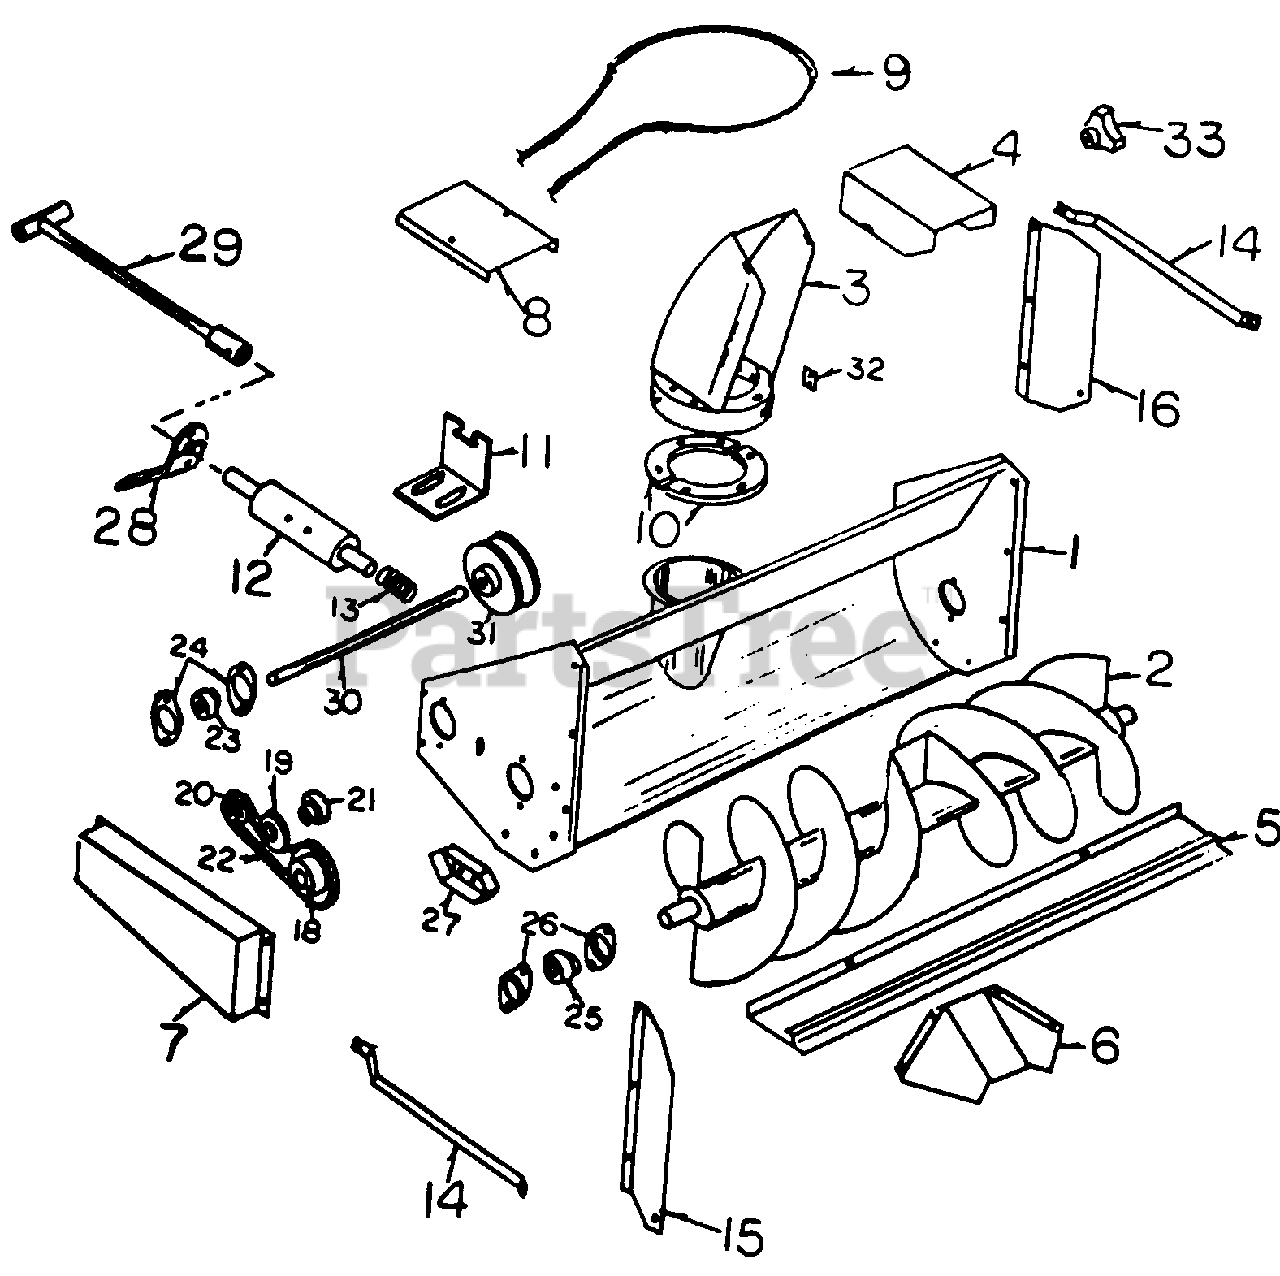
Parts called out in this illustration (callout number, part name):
1	Snow Blower Housing
2	Auger
3	Chute
4	Snow Deflector
5	Snow Blower Bit
6	Snow Retainer
7	Chain Cuard
8	Belt Cuard
9	Cable, 1/8" x 84"
10	Chute Clamp
11	Cable Retainer
12	Cable Pulley
13	Spring
14	Extender Brace
15	Extender, RH
16	Extender, LH
18	Auger Sprocket
19	Idler Sprocket
20	Drive Sprocket(1800)
20	Drive Sprocket(2000)
21	Idler Sprocket Bushing
22	Chain
23	Bearing, 3/4"
24	Bearing Flange, 3/4"
25	Bearing, 1"
26	Bearing Flange, 1"
27	Skid Shoe
28	Cable Pulley Support
29	Handle
30	Shaft
31	Snow Blower Pulley(1800)
31	Snow Blower Pulley(2000)
32	Cable Clamp
33	Wing Nut 2
